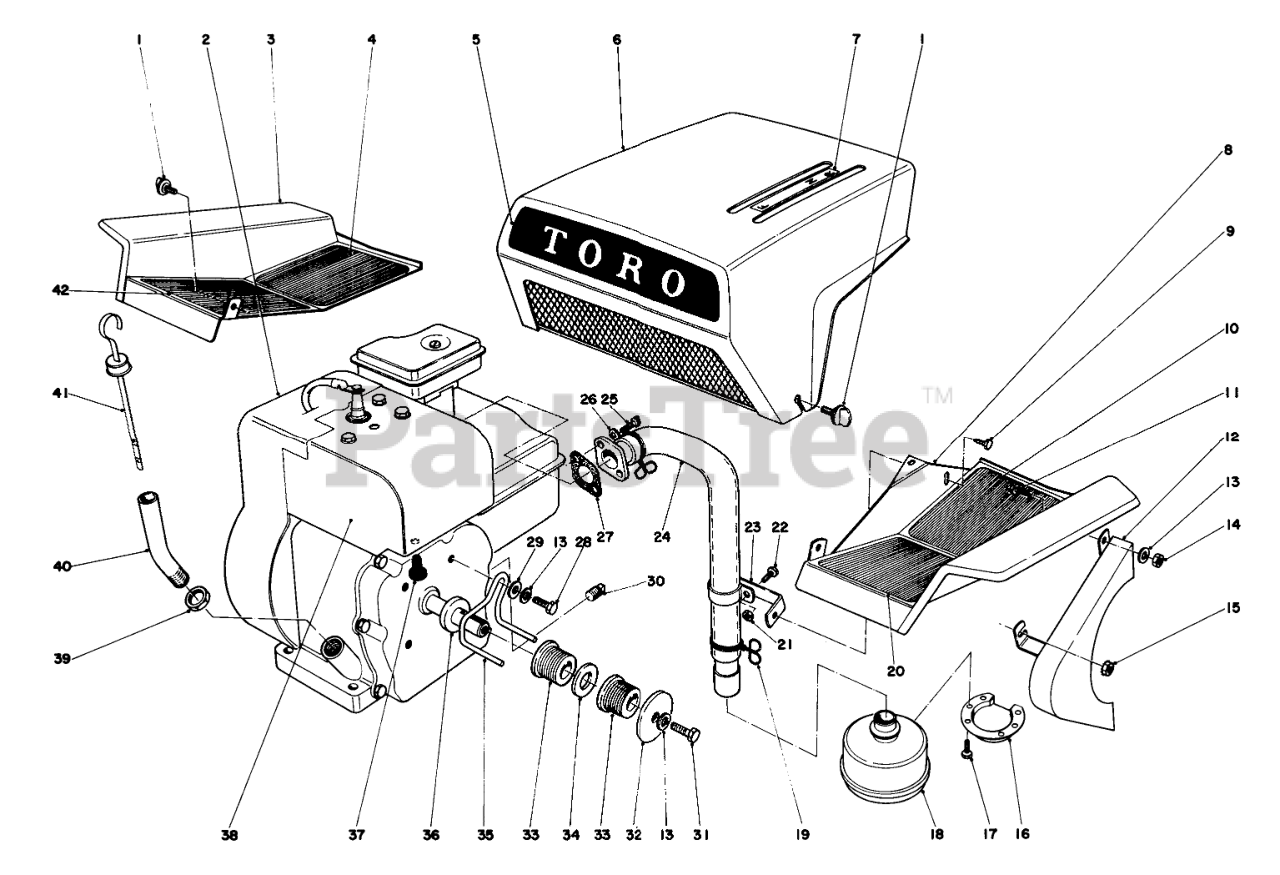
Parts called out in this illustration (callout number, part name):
1	THUMB SCREW WA
2	Engine
3	Fender (Incl. Ref. #4 & 42)
4	Pad, Foot Rest
5	NAME PLATE DECAL
6	Shroud
7	Decal
8	Fender & Insulation (Incl. Ref. #10 & 20)
9	10-16 X 3/8 THDG SCREW
10	Pad, Foot Rest
12	Chain Guard
13	WASHER-LOCK
14	NUT-HEX
15	NUT-KEPS
16	Deflector
17	SCREW W/ENGINE
18	Muffler
19	Bale Tie
20	Pad, Foot Rest
21	NUT-HEX, SIDE DEFORM
22	SCREW-HH
23	Bracket, Muffler Support
24	Exhaust Pipe Assembly (Incl. Ref. #19)
25	SCREW-HSH
26	WASHER-LOCK
27	Gasket
28	SCREW-HH
29	WASHER-PLAIN
30	PLUG-PIPE, SQH
31	SCREW-HH
32	Washer
33	Pulley, Engine Reel
34	WASHER-THRUST
35	Guide
36	Washer
37	BUMPER-RUBBER
38	Deflector
39	PAL NUT
40	Extension Oil Fill
41	DIPSTICK ASM R
42	Pad Foot Rest
